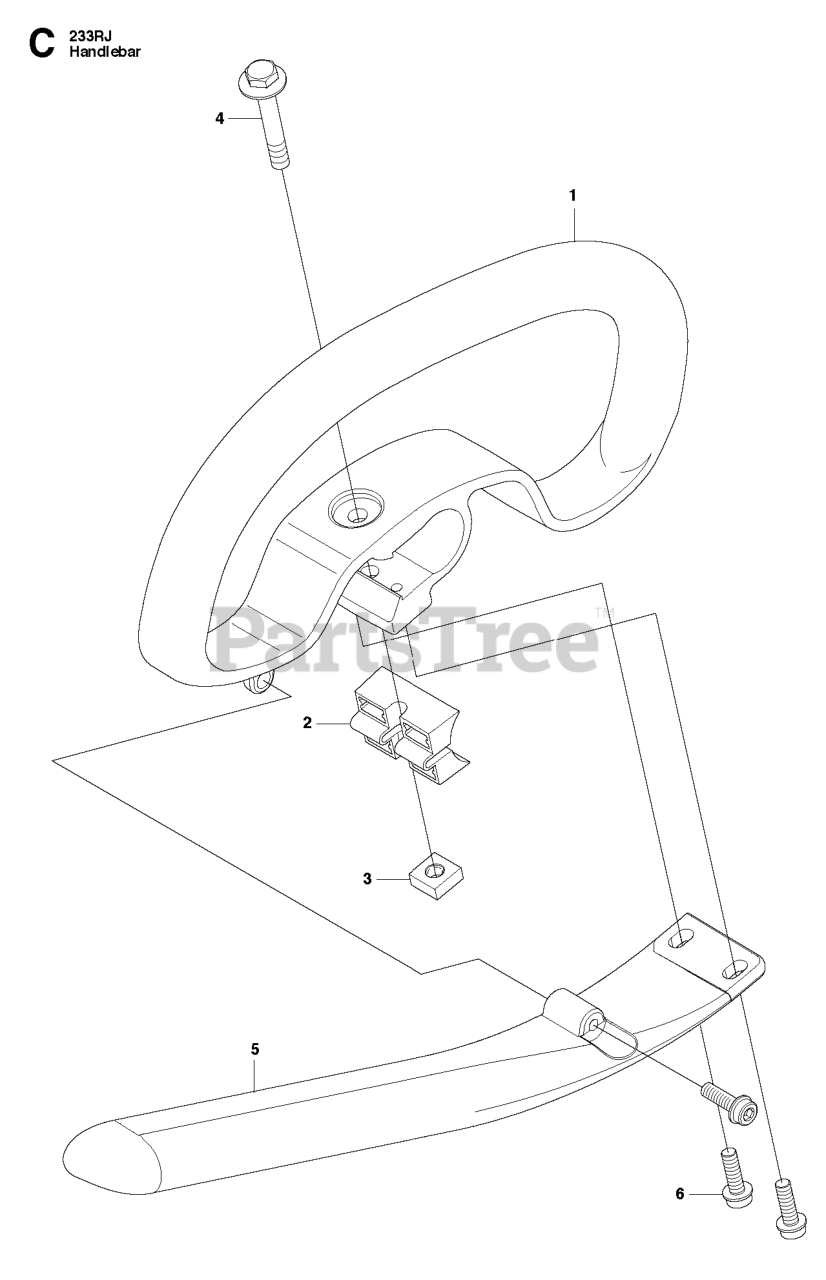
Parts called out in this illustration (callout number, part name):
1	RP HANDLE, LOOP
2	SPACER PLASTIC
4	BOLT FLANGE
5	HANDLE EXTENSION
